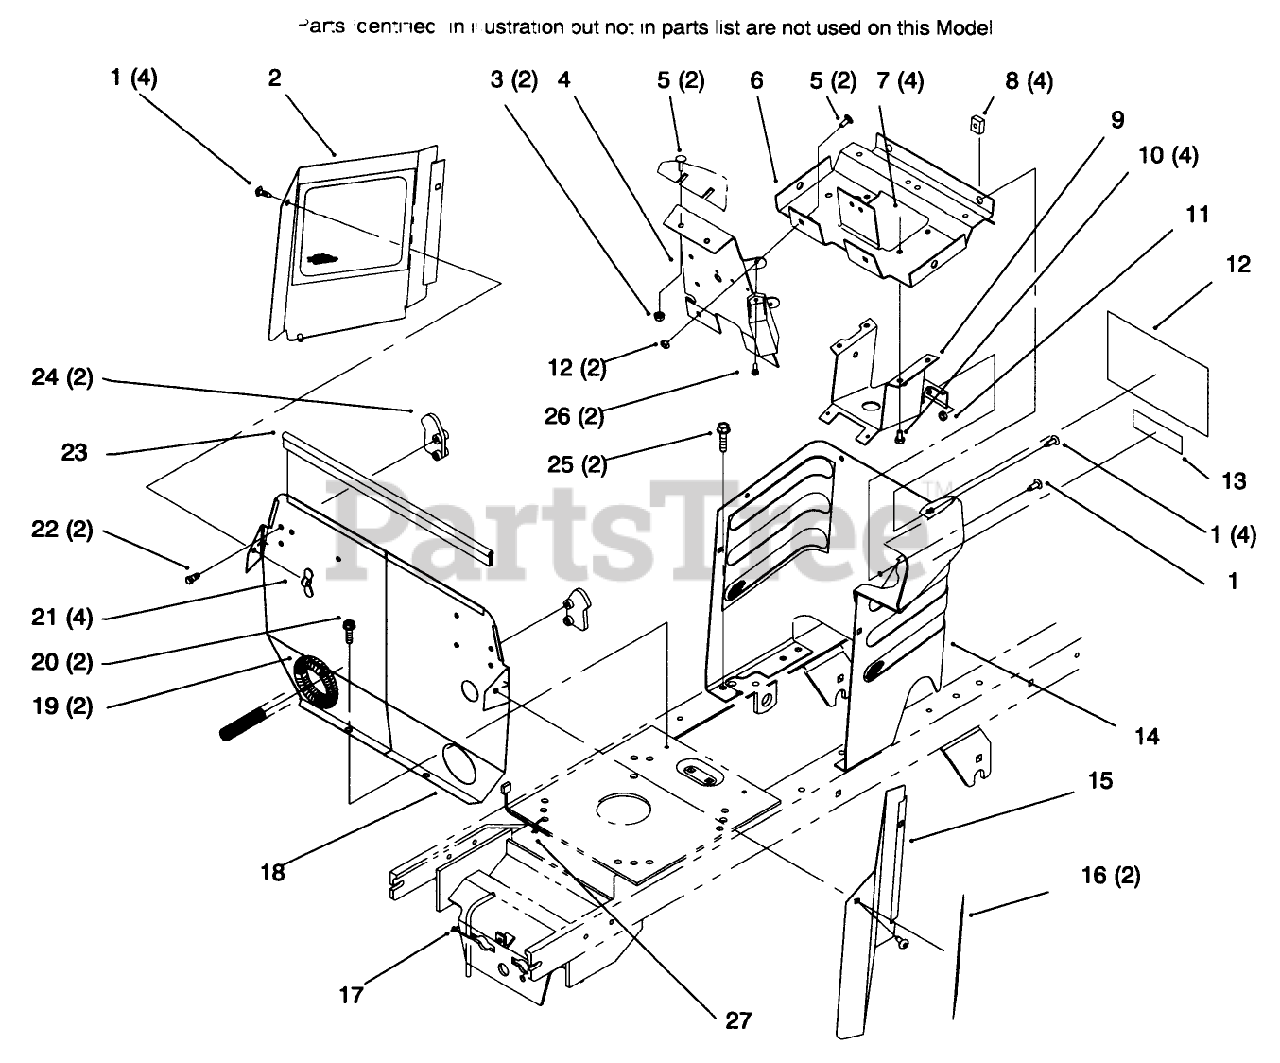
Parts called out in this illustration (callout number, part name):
1	SCREW-HH
2	RH SIDE COVER ASM
3	NUT-KEPS
4	SUPPORT - DASH
5	SCREW-CARR
6	SUPPORT-DASH
7	NUT-HEX
8	NUT RETAINER - J TYPE
9	BRACKET-COLUMN, LOWER
10	SCREW-HH
11	NUT-LOCK, NI
12	DECAL-DANGER
12	DECAL-SLOPE/HYDRO
13	DECAL-INSTRUCTION
15	LH COVER ASM
16	DECAL - 267-H
17	TIE-CABLE
18	FIREWALL
19	COVER-SHAFT, DRIVE
20	SCREW-HWH
21	NUT-WING
22	SCREW-PLASTITE
23	TRIM-SEAL, FIREWALL
24	LATCH-HOOD
25	SCREW-HWHTF
26	SCREW-PPHTF
27	TIE-CABLE
